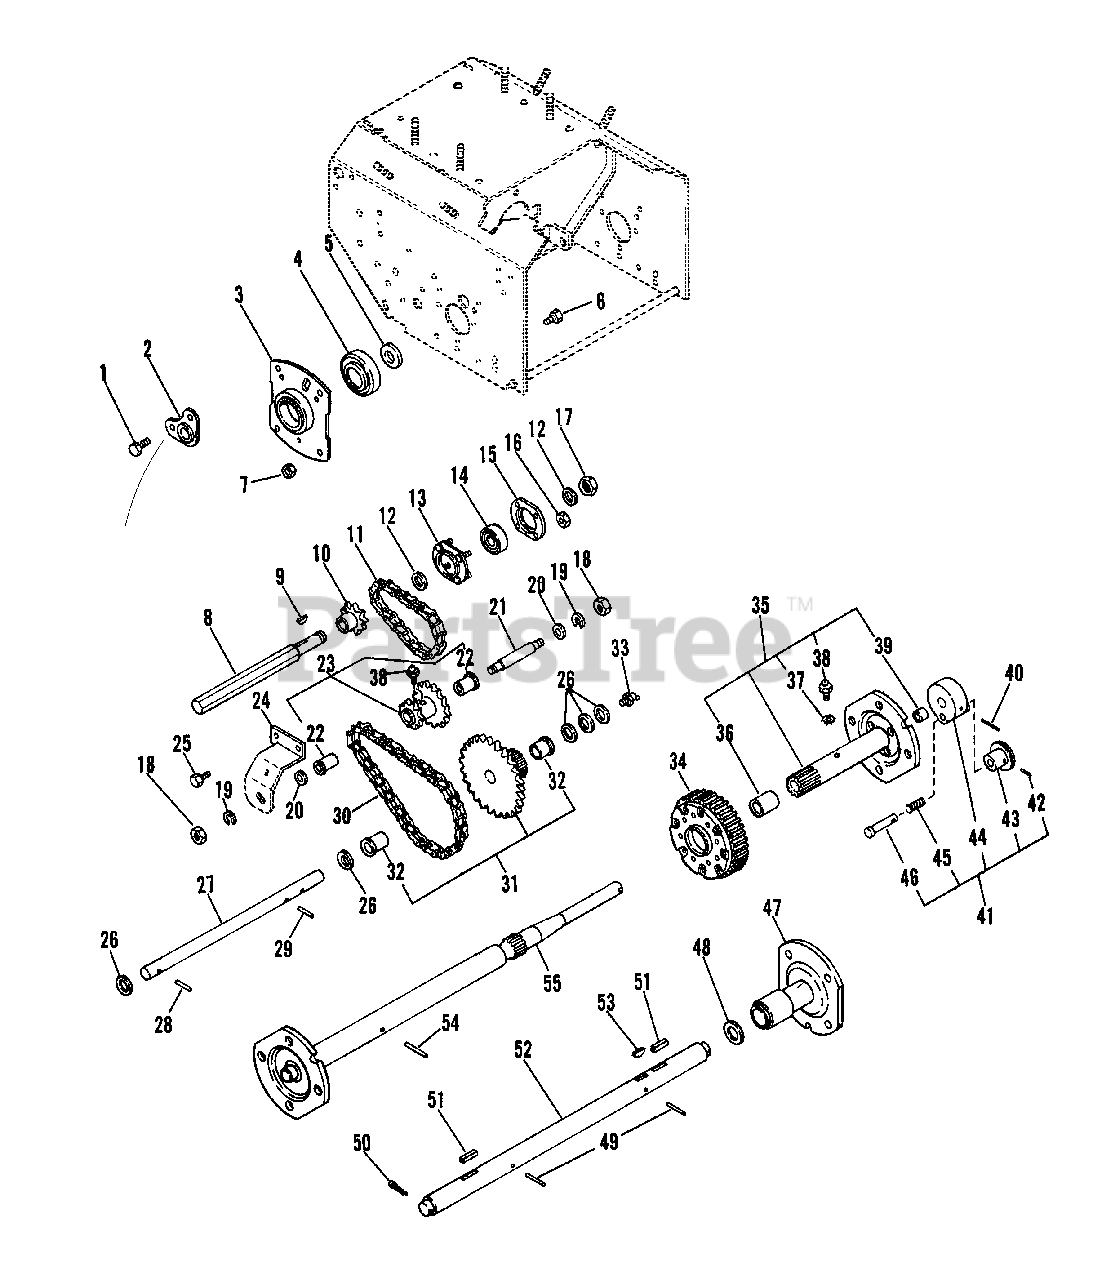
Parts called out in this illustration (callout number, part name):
1	SCR-TAP .250-20X.37 HWH PL TR
2	SUPPORT, SHAFT
3	SUPPORT, BEARING
3	BEARING RETAINER
4	BRG-BALL 1.13X2.18X.63
4	BRG-BALL 1.13X2.19X.63
4	BSHG-FLG.875X1X.625X1.250 BR
4	BSHG-FLG .750X1.000X.625X1.250
5	WSHR-FL-STL .755X1.375X.125
5	WSHR-FL-STL 1.140X1.718X.134
6	SCR-SLTR-SERNK .25-20X.62 PL
6	BLT-SERNK SL .25-20X.50 PL
7	NUT-LK-FLG .250-20 PL
8	HEX SHAFT
9	KEY-WDRF .125X.625X.250 SAE5
10	9 TOOTH SPROCKET
11	CHAIN
11	IDLER CHAIN
12	WSHR-FL-STL .531X1.062X.095 PL
13	BEARING FLANGE
14	BRG-BALL .500X1.38X.437
15	BEARING FLANGE
16	NUT-LK DUAL FACE 10-24 PL
17	NUT-LK-CTR .50-20 PL
18	NUT-HEX .375-16
19	WSHR-LK .375X.130
20	WSHR-FL-STL .382X.812X.062
21	REDUCTION SHAFT
22	BSHG-SLV .500X.625X.500 BR
23	SPROCKET ASSEMBLY
24	SUPPORT, SHAFT
24	CLUTCH STOP
25	SCR-TAP .250-20X.50 HXSLHDPL
26	WSHR-FL-STL .630X1.005X.062 PL
27	PINION SHAFT
28	PIN-ROLL .156X1.00
29	PIN-ROLL .125X1.00
30	PINION CHAIN
31	PINION AND SPROCKET ASSY.
31	PINION & SPROCKET ASSEMBLY
32	BSHG-FLG .625X.750X.500X.875BR
33	HYDRAULIC DRIVE FITTING
34	SPUR GEAR, FELLOWS 35T .750 ID
34	GEAR, SPUR
34	DIFFERENTIAL ASSEMBLY
35	L.H. AXLE ASSEMBLY
35	L.H.AXLE ASSEMBLY
36	BSHG-SLV .750X.814X .750 BRZ
37	WSHR-LK .250X.047 LT PL
38	SPIN DRIVE ZERK FITTING
39	BSHG-SLV .562X.625X.625 BRZ
40	PIN-GRV .250X1.75 TP C
41	LOCKOUT HUB ASSEMBLY
42	PIN-ROLL .093X1.00
44	LOCKOUT HUB
45	SG-COMP .028X.34X1.062 WLD75
47	WHEEL HUB
48	WSHR-FL-STL .755X1.375X.125
48	WSHR-FL-STL .880X1.380X.062
49	PIN-ROLL .188X1.25
50	PIN-COTR .12 X 1.25 PL
51	KEY-FTHR .188X1.25X.187 SAE
52	AXLE SHAFT
53	KEY-WDRF .25X.875X.375 SAE A
53	KEY-WDRF .25X.750X.313 SAE91
54	PIN-ROLL .188X1.50
55	R H AXLE
